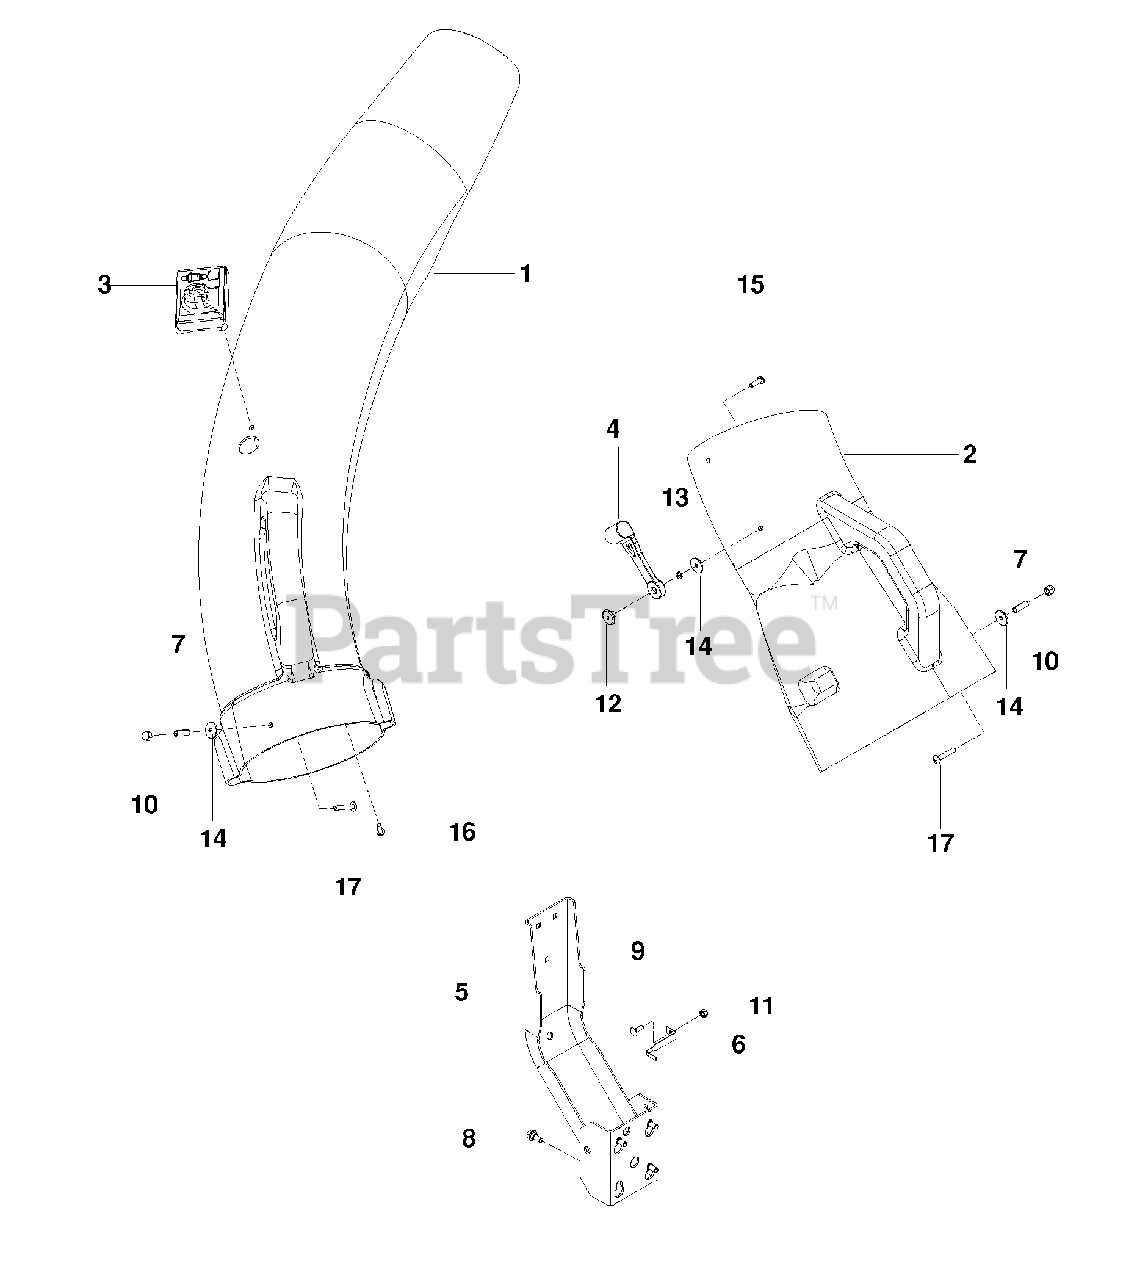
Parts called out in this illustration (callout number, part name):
1	CHUTE, UPPER
2	CHUTE, MIDDLE
3	INDICATOR, BAG DUMP
4	LATCH, HOOD
5	SUPPORT ASSY
6	STOP BRACKET
7	SPACER, SPLIT
8	BOLT 5/16-18 THD FRM
9	RHSNB 1/4-20 x 3/4
10	NUT 10-24 ACORN
11	NUT 1/4-20 HEX NYLOC
12	WELD NUT, PLATED
13	WASHER 3/16 LOCK
14	WASHER 3/16 x 3/4
15	SCREW 10-24 x .625 MACH
16	SCREW 10-14 x 1/2 SPEC
17	SCREW 10-24 x 11/8
